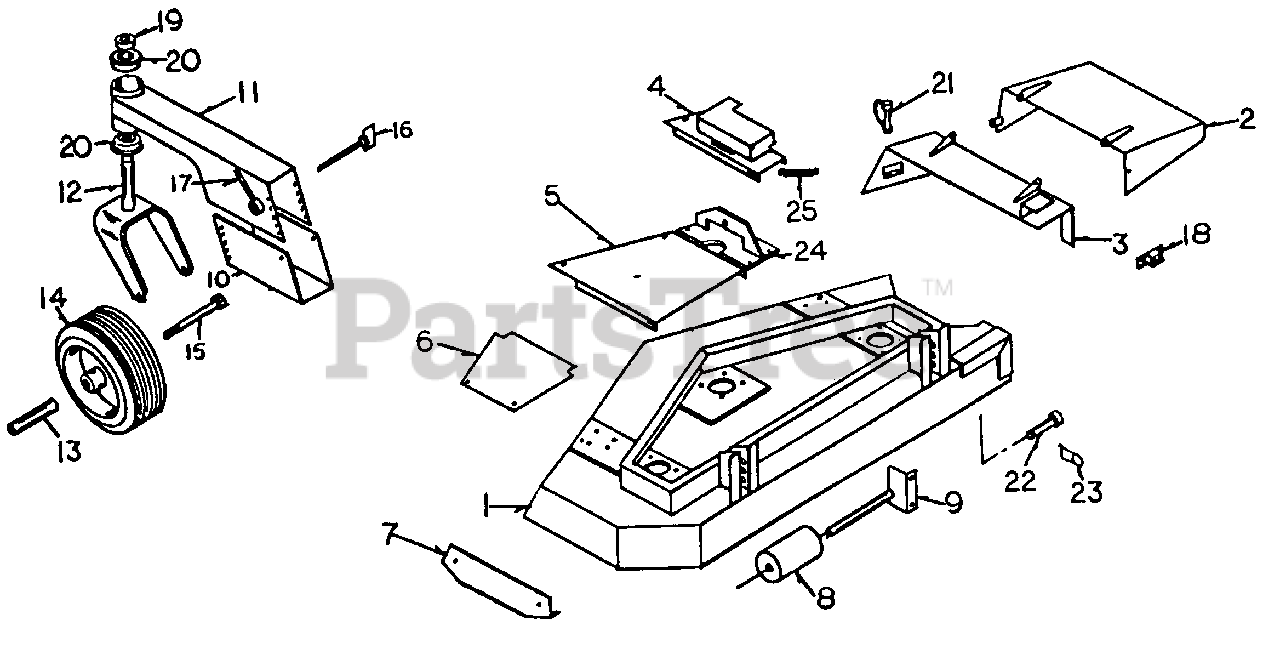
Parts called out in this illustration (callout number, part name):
1	Deck
3	Foot Guard Mount
8	Antl-scalp Roller
9	Shaft & Bracket
10	Gauge Wheel Mount Bracket
11	Gauge Wheel Mount
12	Fork
14	Gauge Wheel Assembly
15	Hex Bolt, 1/4-20 x 4 1/2", GR5 0
18	10 Amp Circuit Breaker
19	Set Collar, 1"
23	Hair Pin Cotter
24	Deck Mount
